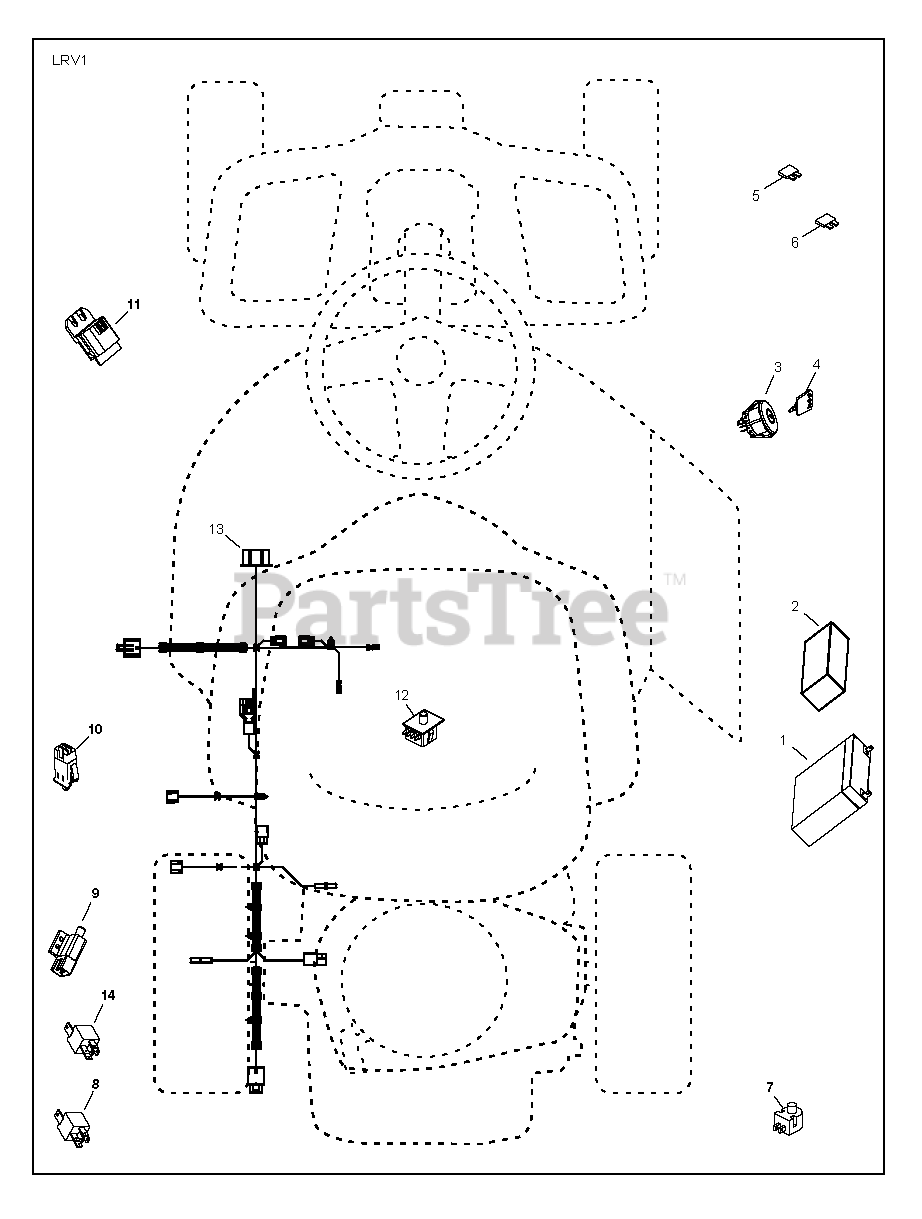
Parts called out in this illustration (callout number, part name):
1	BATTERY.2.8H.LRVA TBR
2	FOAM.POLYURETHANE
3	SWITCH.IGN.DELTA.W.LGH.ROS
4	KEY.CHAIN.BLISTER.PACK.CRF.INT
6	FUSE, 40A
7	PLUNGER SWITCH (COLOR:OLIVE)
8	RELAY, 40A
9	SWITCH INTERLOCKT
10	SWITCH INTERLOOK PUSH-IN
11	MODULE.STARTING.RECOIL.LRV
12	SWITCH.SEAT.DP W/RAMPS
13	HARNESS, IGN, ELECTSTART, LRV
14	RELAY.ASSY.T
